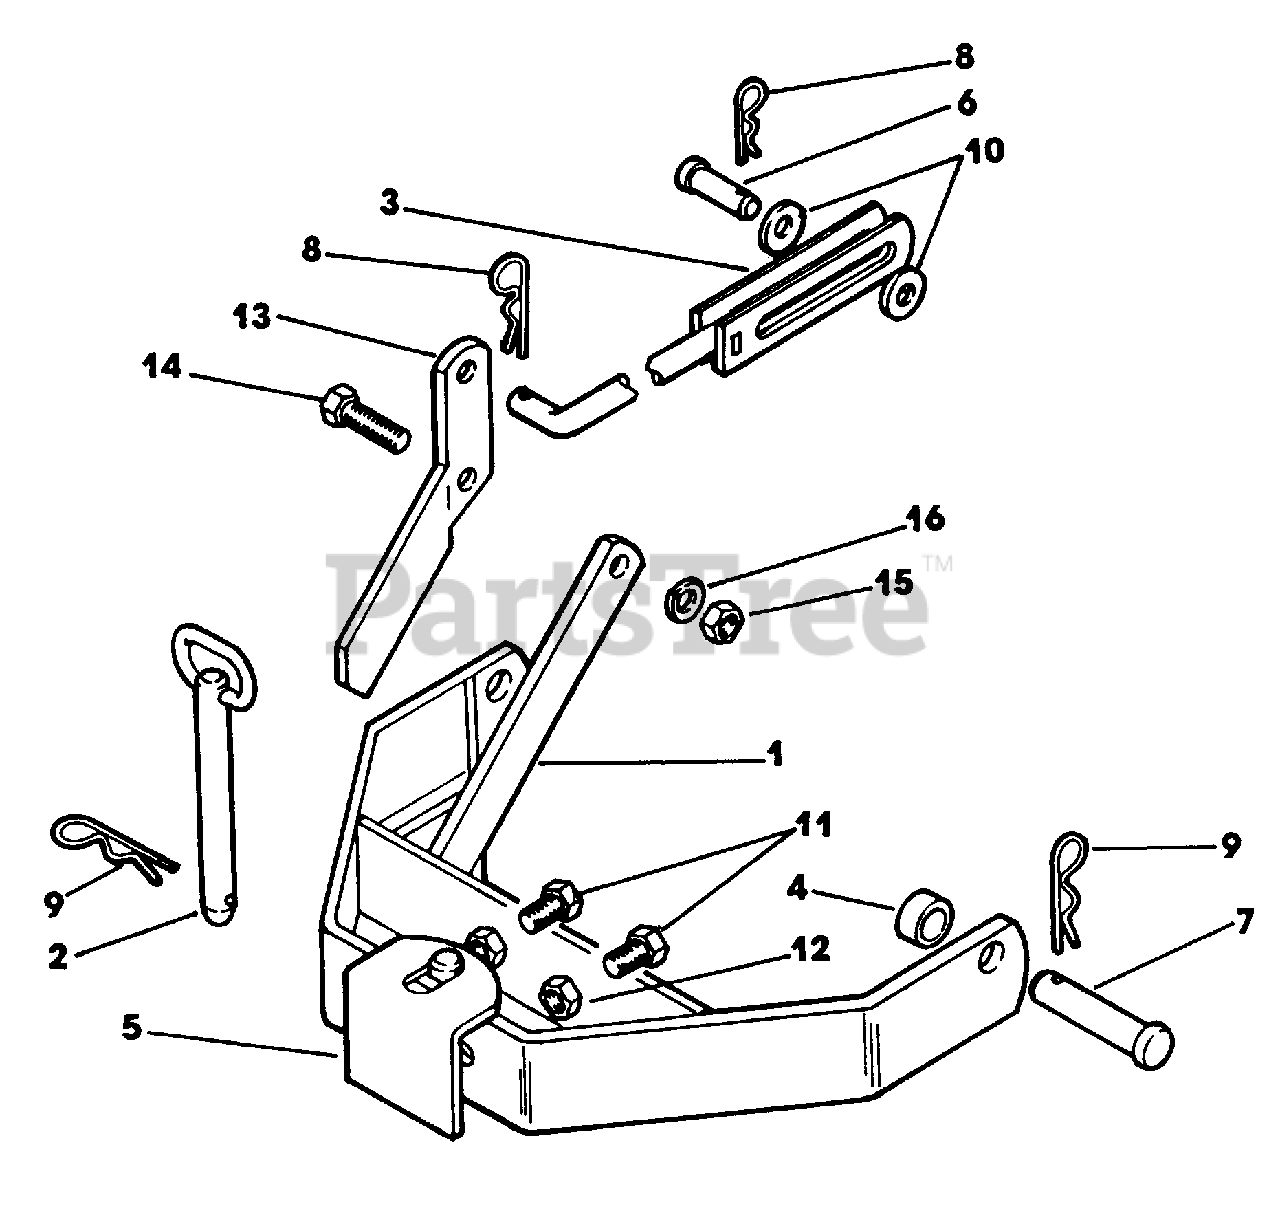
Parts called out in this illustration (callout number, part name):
1	Sleeve Hitch Assembly
2	Hitch Pin Assembly
3	Lift Rod Assembly
5	Stabilizer Plate
6	Clevis Pin
7	Clevis Pin
8	Spring Clip
9	Spring Clip
10	Washer, Flat
11	Cap Screw, Hex Hd
12	Nut, Hex Jam
13	Lift Arm Extension Assembly
14	Cap Screw, Hex Hd
15	Nut, Hex
16	Washer, Spring Lock
